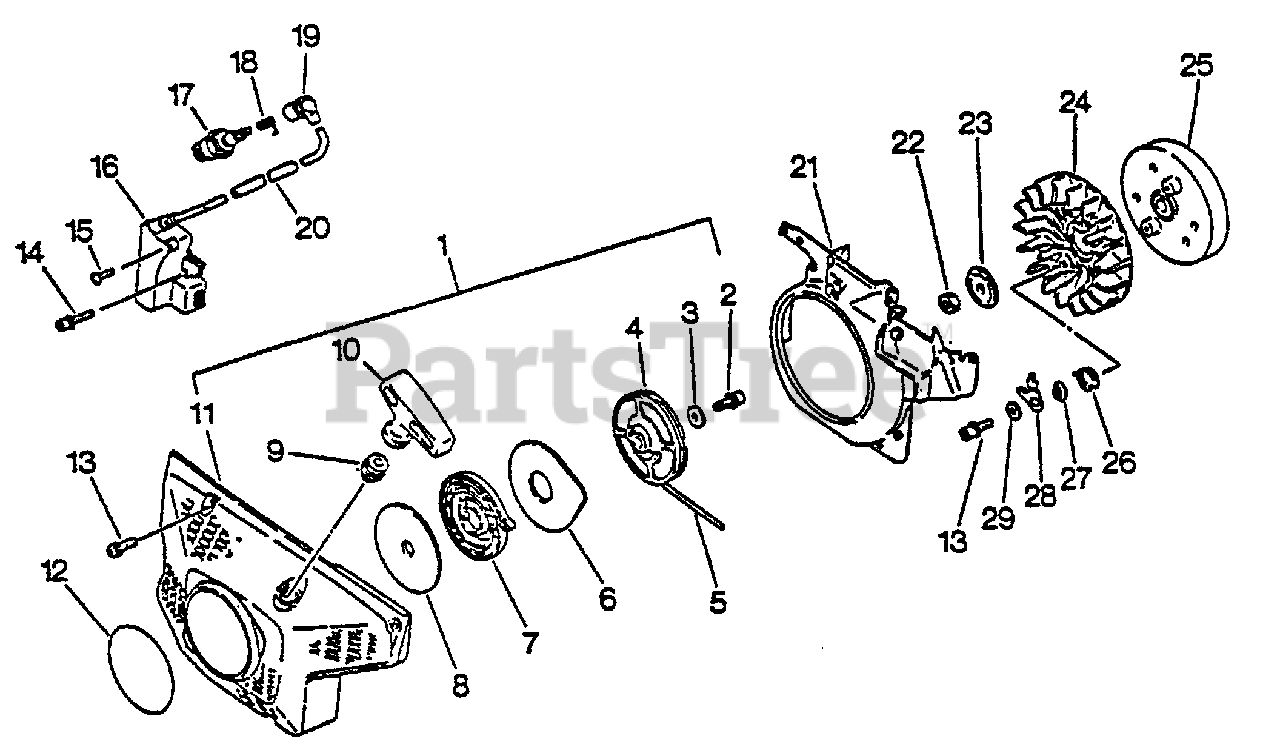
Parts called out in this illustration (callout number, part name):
1	STARTER ASSY
2	BOLT 5×14
3	WASHER 5.5×12×0.8
4	REEL, ROPE
5	ROPE, STARTER 4.0×950
6	PLATE, STARTER
7	SPRING, RECOIL
8	PLATE, STARTER
9	GUIDE, ROPE
10	GRIP, STARTER
11	CASE, STARTER
12	LABEL - ECHO
13	BOLT 5×20
14	BOLT 4×20
15	SCREW 4×8
16	COIL, IGNITION
17	SPARK PLUG - BPM6A
18	TERMINAL, SPARK PLUG
19	CAP, SPARK PLUG
20	PIPE
21	SHIELD, FAN
23	WASHER 8.2×31×0.8
25	FLYWHEEL
26	SPRING, RETURN
28	PAWL, STARTER
29	WASHER 5.5×12×0.8
